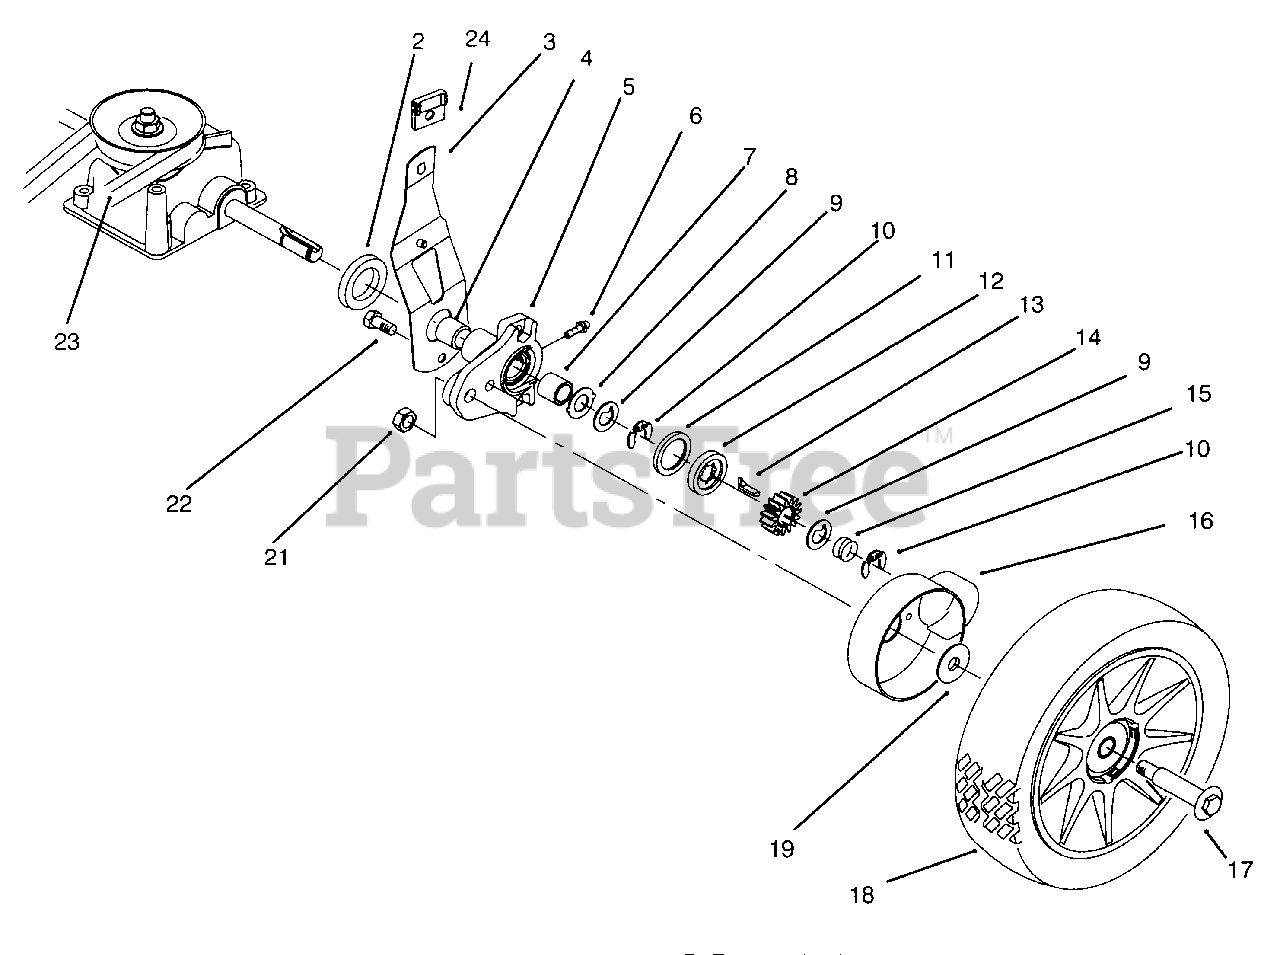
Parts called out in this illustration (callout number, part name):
2	Spacer-Axle Shaft
3	Spring Arm Ass'y
5	Pivot Arm Ass'y-Rear (Incl. Ref.#4, 6, & 8)
6	Fitting-Grease
8	Washer-Thrust Pivot Arm
9	Washer-Thrust, Keyed
10	Ring-Klip. Special
11	Ring-Friction
12	Washer-Clutch, Plastic
13	Key-Rocking, LH
14	Gear-Pinion
15	Spring-Compression
16	Cover Wheel
17	Bolt-Wheel
18	Wheel Ass'y-8"
19	Washer-Stepped
